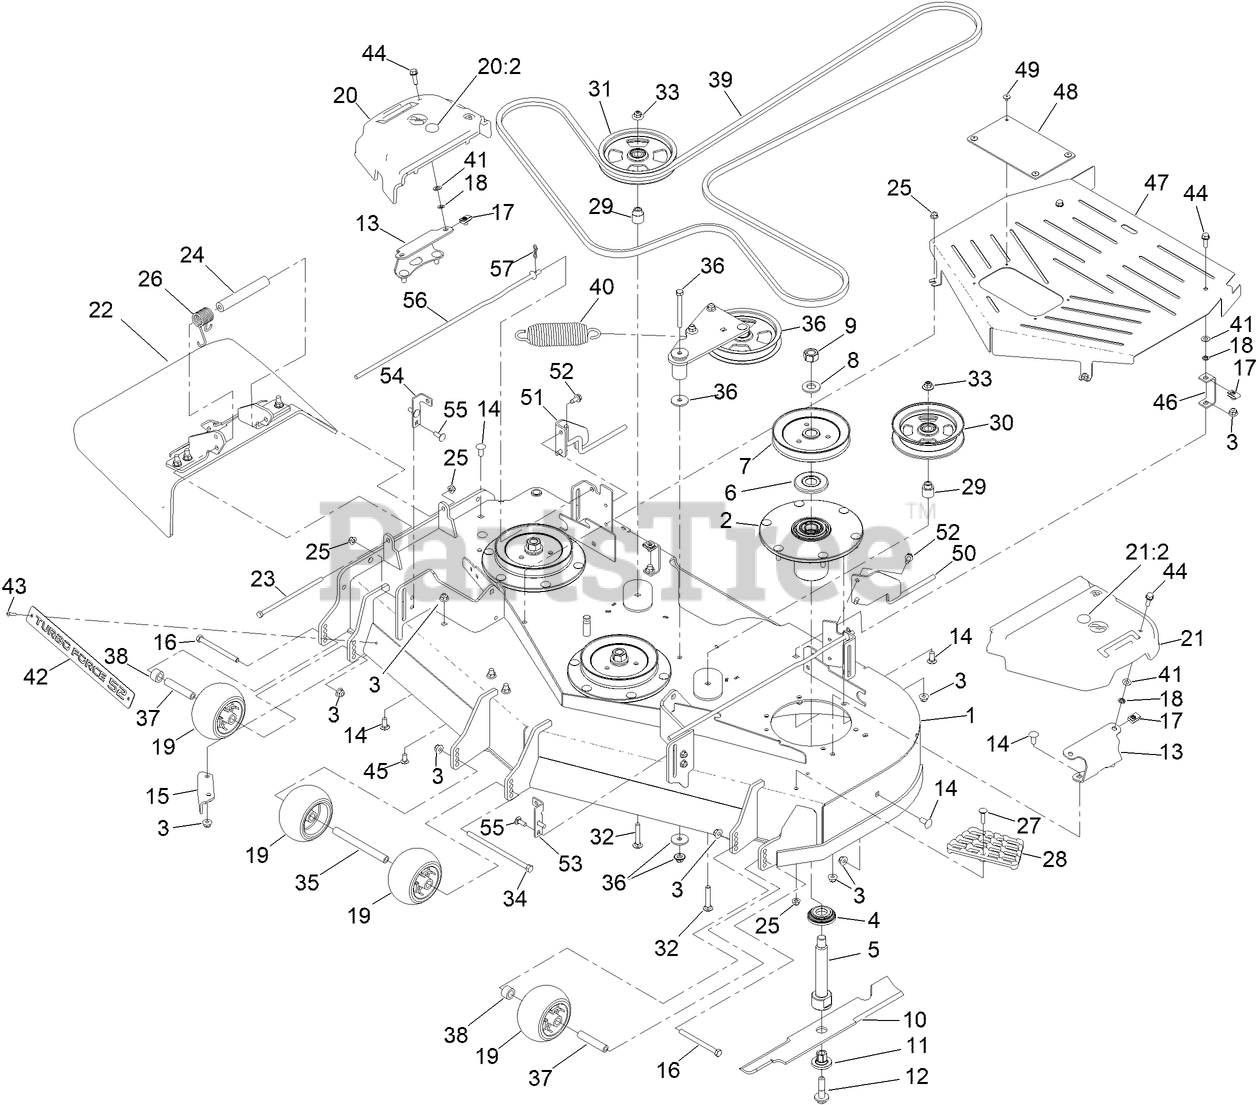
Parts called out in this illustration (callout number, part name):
1	DECK DECAL ASM
2	SPINDLE ASM
3	NUT-HF, NI
4	GUARD-BOTTOM
5	SHAFT-SPINDLE
6	GUARD-BEARING, TOP
7	SHEAVE-BLADE DRIVE 6.50
8	WASHER
9	NUT-HEX
10	BLADE-FLOW, HIGH
11	BUSHING-HEX
12	SCREW-SEMS
13	BRACKET-COVER, BELT
14	SCREW-CARR
15	BAFFLE-DISCHARGE
16	SCREW-HH
17	NUT-U
18	NUT-PUSH
19	ROLLER-SCALP, ANTI
20	RH BELT COVER ASM
20:2	PLUG-PLASTIC
21	LH BELT COVER ASM
21:2	PLUG-PLASTIC
22	RUBBER DEFLECTOR ASM
23	SCREW-HH
24	SPACER
25	NUT-HF, NI
26	SPRING-TORSION
27	SCREW-CARR
28	STEP-DECK
29	BUSHING, IDLER
30	PULLEY-IDLER, FLAT
31	PULLEY-IDLER, FLAT
32	SCREW-CARR
33	NUT-FLANGE, NI
34	SCREW-HH
35	SPACER-WHEEL
36	IDLER ARM ASM
37	TUBE-SHAFTING
38	TUBE-SPACER
39	BELT-V
40	SPRING-EXTENSION
41	WASHER-THRUST
42	PLATE-TURBO FORCE [BLACK]
43	RIVET-TRIFOLD
44	SCREW-HHF
45	SCREW-CARR
46	BRACKET-GUARD
47	GUARD-CENTER BELT 52
48	SHIELD-RUBBER
49	RIVET-POP
50	SUPPORT-LOWER LH
51	SUPPORT-LOWER RH
52	SCREW-HWHTF
53	BRACKET-SUPPORT, LH
54	BRACKET-SUPPORT, RH
55	BOLT-CARR
56	ROD-SKIRT, LOWER
57	PIN-COTTER, LOCKING
